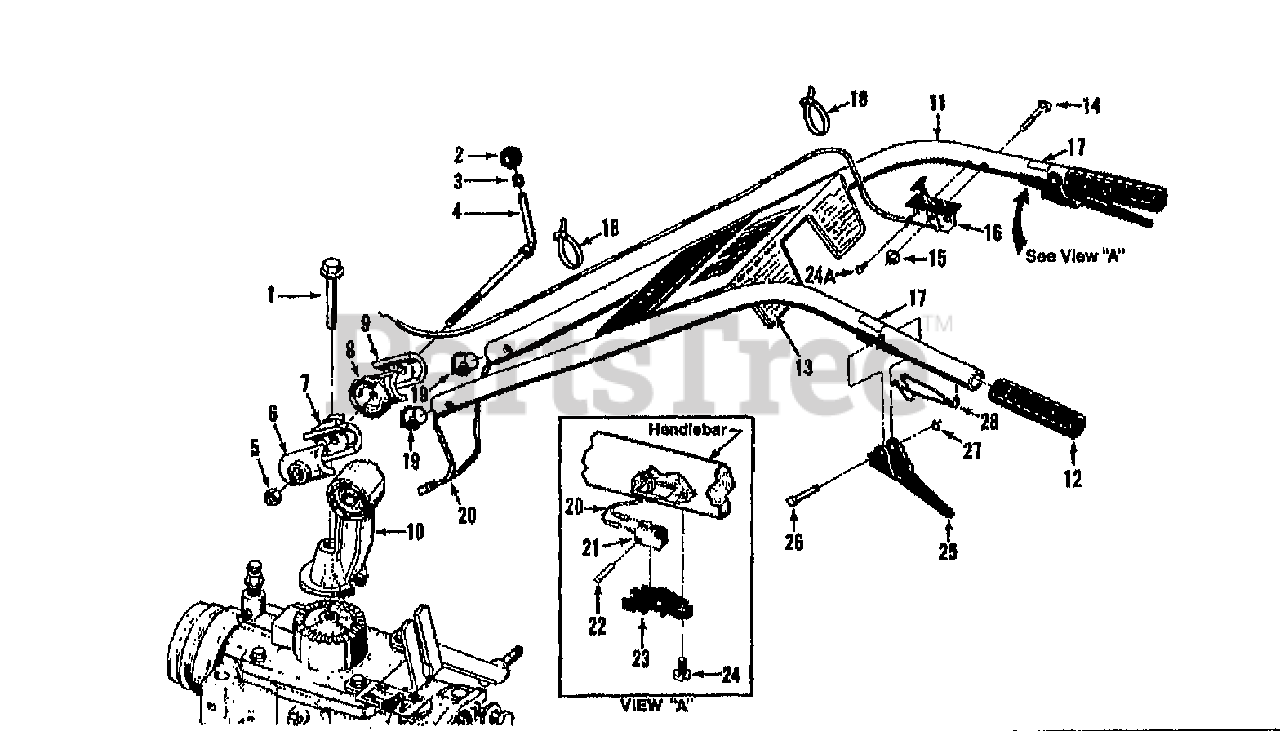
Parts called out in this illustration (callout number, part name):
1	BOLT 1/2-13X3.5 FH GR5
2	KNOB-CONTROL (INCL. 3)
3	RING-TOLERANCE .5325 ID
4	STUD-H/BAR W/NUT & RING (INCL. 2,3 & 5)
5	NUT-HEX JAM 1/2-13
6	CLAMP-LH HORSE 1021-1
7	RATCHET-H/BAR RED 2542-1
8	RATCHET-RH RED HORSE 2542-2
9	CLAMP-RH HORSE 1021-2
10	BASE-H/BAR RED 2534A
11	ASSM-HANDLEBAR W/GRIPS (INCL. 2 OF EA. 12, 17 & 28 AND ONE 13)
12	GRIP-H/BAR SMOOTH
13	DECAL-CONTROL PANEL HORSE
13	DECAL-CONTROL PANEL (11HP)
14	BOLT-CH 1/4-20X2.00 ZP
15	NUT-HF/LK 1/4-20 ZP
16	CABLE-THROTTLE 7 I/C B&S {12068/069/080/081/087}
16	CABLE-THROTTLE 7&8 B&S {12074/075/088/089/090}
16	CABLE-THROTTLE 8HP OPC {12070/071/082/083}
17	DECAL-FWD INTERLOCK
18	TIE-RED
19	RETAINER-HARNESS H/B OPC
20	HARNESS-WIRE OPC HORSE
21	SWITCH-H/B OPC
22	PIN-LK .11X.58 HORSE OPC
23	HOUSING-SWITCH OPC
24	SCR-HW M10-24X.5 STH ZP
24A	SCR-PHS M10-32X.5 STH ZP
25	LEVER-HORSE OPC
26	PIN-PIVOT OPC LEVER
27	RING-KLIP 5304-25
28	SPRING-H/B LEVER
